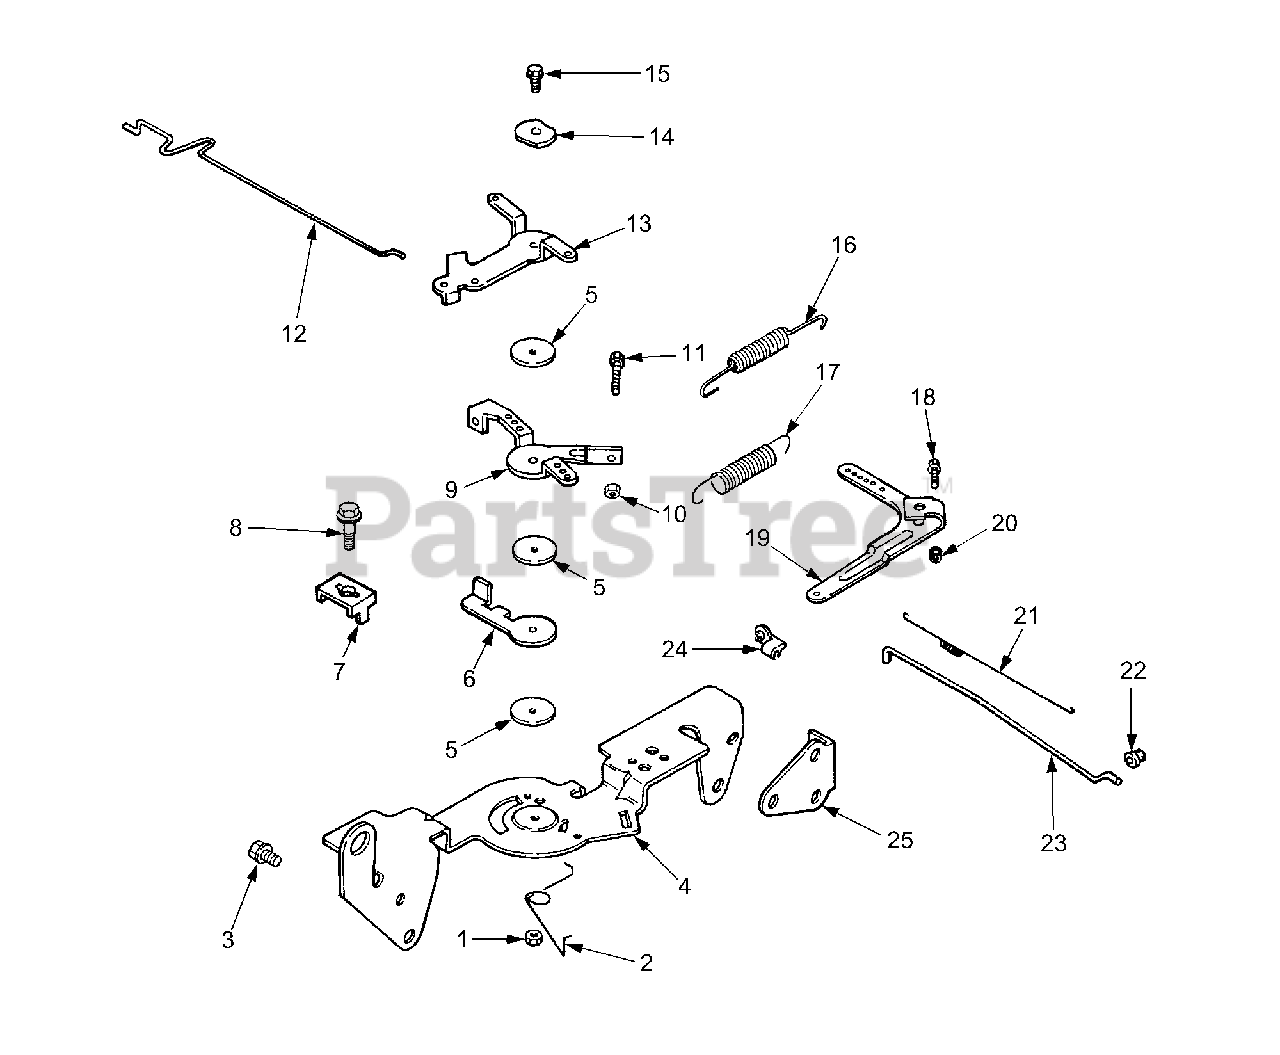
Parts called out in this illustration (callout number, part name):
1	Nut, Hex Lock M5 x 0.8
2	Spring, Choke Return
3	Screw, Hex Flange M6 x 1.0 x 16
4	Bracket, Control
5	Washer, Plain 5.5 mm
6	Lever, Throttle Actuator
7	Clamp,Cable,
8	Screw, Hex Flange M5 x 0.8 x 16
9	Lever, Throttle Control
10	Nut, Hex M4 x 0.7
11	Screw, Hex Cap M4 x 0.7 x 30
12	Linkage, Choke
13	Lever, Choke
14	Washer, Spring 1/4"
15	Screw, Hex Flange M5 x 0.8 x 20
16	Spring, Throttle Limiter
17	Spring, Governor
18	Screw, Carriage
19	Lever, Governor
20	Nut, Hex Flange M6 x 1.0"
21	Spring, Linkage
22	Bushing, Linkage Retaining
23	Linkage, Throttle
24	Bushing, Linkage Retaining
25	Bracket Support
